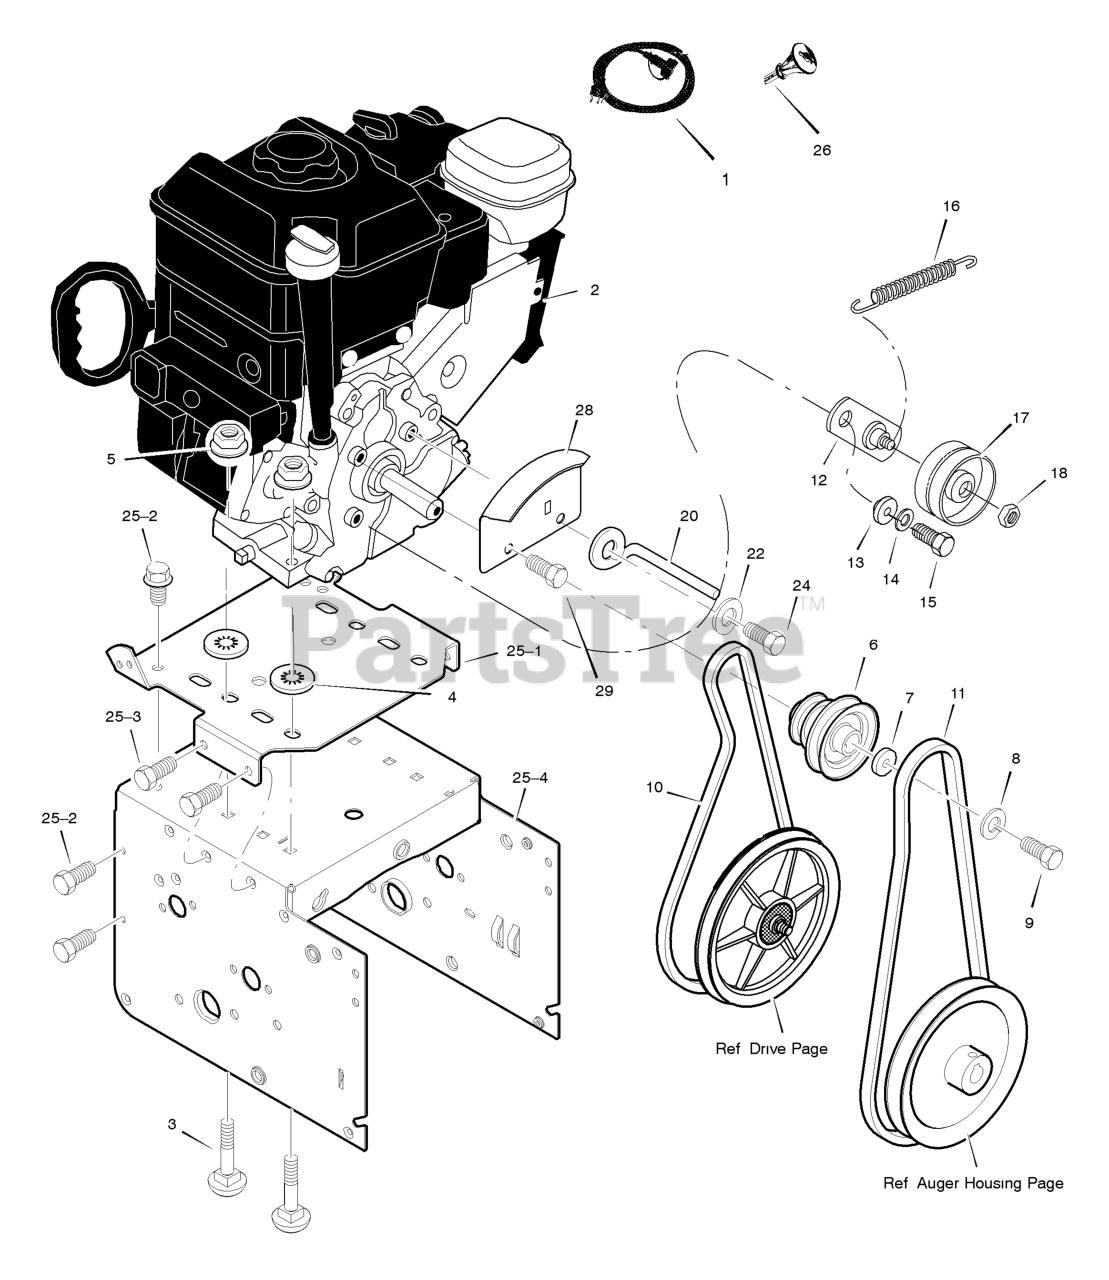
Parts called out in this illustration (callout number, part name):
1	CORD, Electric, 10FT. 110V
2	ENGINE
3	BOLT, CARRIAGE 5/16-18
4	RETAINER, PUSH
5	NUT 5/16-18
6	PULLEY, ENGINE
7	WASHER
8	WASHER
9	SCREW, 3/8-24 x 1.00
10	BELT, V 3L
11	BELT, V 4L
12	BRACKET ASSEMBLY, IDLER
13	BUSHING, IDLER BRACKET
14	WASHER
15	SCREW 5/16-24 X 0.75
17	PULLEY, IDLER
18	NUT, JAM 3/8-16
20	GUIDE, ROD BELT
22	WASHER, SPTLK .31X.58X.08
24	SCREW, 5/16-24 x 0.75
25	FRAME ASSEMBLY
25-1	PLATE, ENGINE MOUNT
25-2	SCREW 1/4-20 X .63
25-3	SCREW 5/16-18 X .50
25-4	FRAME, MOTOR BOX
26	KEY, IGNITION
28	BRACKET, ENGINE SHIELD
